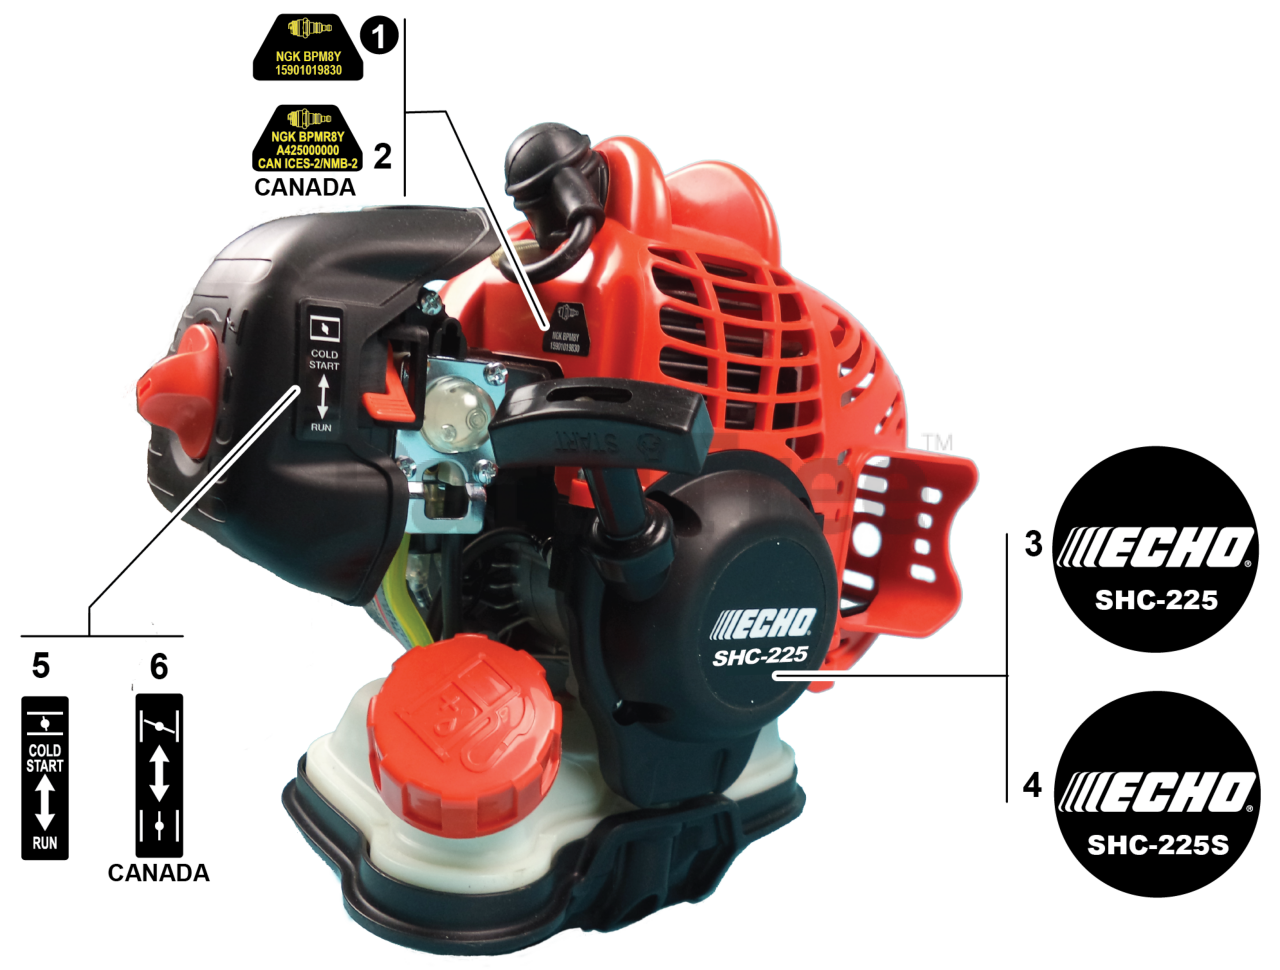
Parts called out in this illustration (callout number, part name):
1	LABEL - SPARK PLUG - BPM8Y
2	LABEL - SPARK PLUG - BPMR8Y
3	LABEL - STARTER - SHC-225
4	LABEL - STARTER - SHC-225S
5	LABEL - CHOKE
6	LABEL - CHOKE
